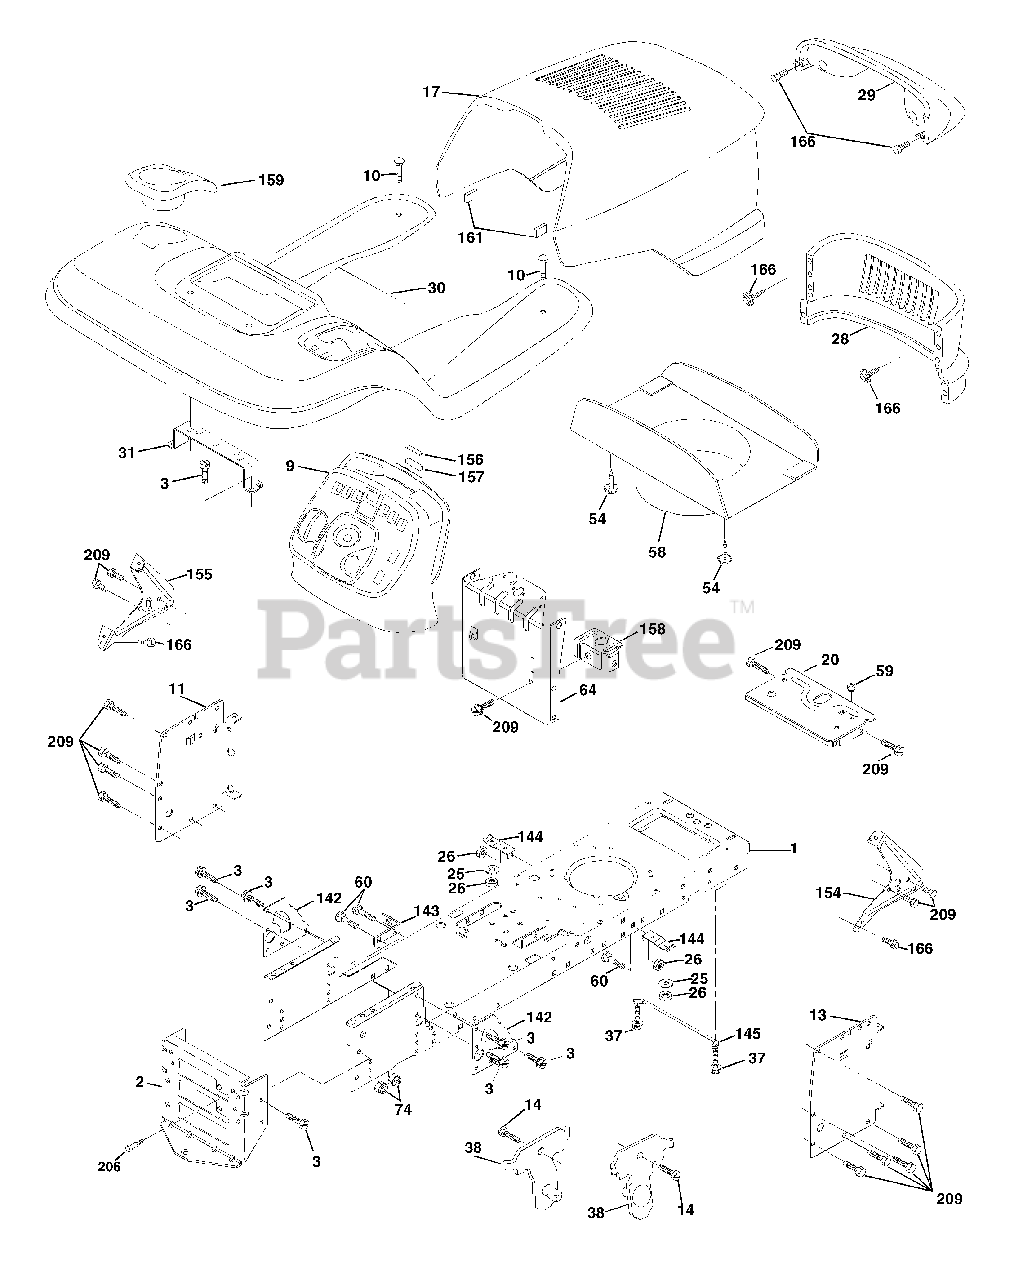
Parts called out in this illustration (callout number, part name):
1	Chassis
2	Drawbar
3	Screw 3/8-16x3/4
9	Dash
10	Bolt 3/8-16 x 1
11	Panel Dash Lh
13	Panel Dash Rh
14	Screw Thdrol 3/8-16 x 1/2
17	Hood
20	Plate Battery
25	Washer 13/32 X 13/16 X 12 Ga
26	Nut Lock Hex W/Ins 3/8-16 Unc
28	Grille
29	Lens
31	Bracket Fender
37	Screw Thdrol 6/16-18 x 1/2 TYT
38	Bracket, Asm. Pivot Mower Rear
54	Screw Hex Wshd 8-18 x 7/8
58	Duct Hood
59	Bushing Snap
60	Bolt Rd Hd Sqnk 3/8-16 Unc x 3/4
64	Dash Lower
74	Nut Crownlock 3/8-16 Unc
142	Plate Reinforcement STLT
143	Bracket Swaybar Chassis
144	Bracket Footrest
145	Rod Pivot Chassis/Hood
154	Bracket Dash Rh
155	Bracket Dash Lh
156	Striker Plate
157	Magnet Stealth
158	Bracket Parking Brake
159	Cupholder
161	Extrusion Bumper
166	Screw Hw Hd Hi-Lo #13-16 x 3/4
206	Bolt Shoulder 5/16-18
209	Screw Hexwsh Thdrol 3/8-16 x 3/4
